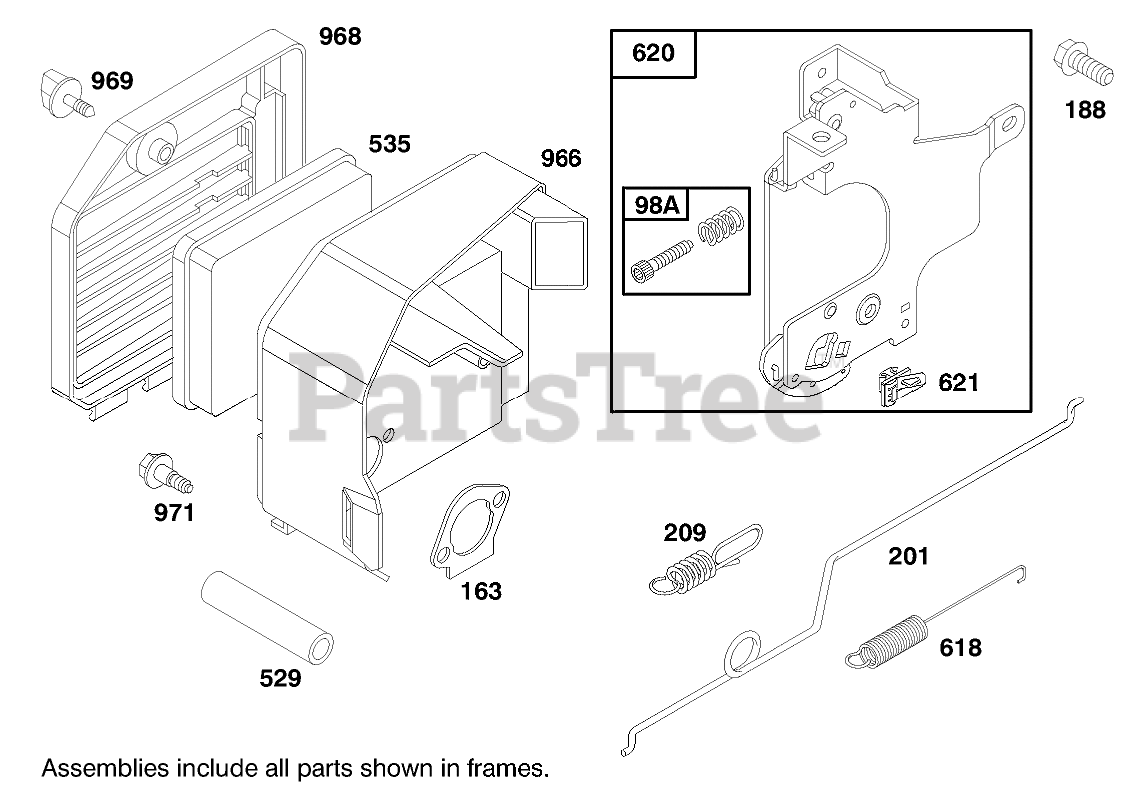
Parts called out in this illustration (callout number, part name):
98A	SPEED ADJUST. SCREW ASM
163	AIR CLEANER GASKET
188	Plug-Pipe
201	GOVERNOR LINK
209	GOVERNOR SPRING
529	TUBE - BREATHER
535	FILTER ELEMENT
618	RETURN SPRING
620	CARBURETOR BRACKET
621	STOP SWITCH
966	AIR CLEANER BASE
968	AIR CLEANER COVER
969	AIR CLEANER SCREW
971	AIR CLEANER SCREW
